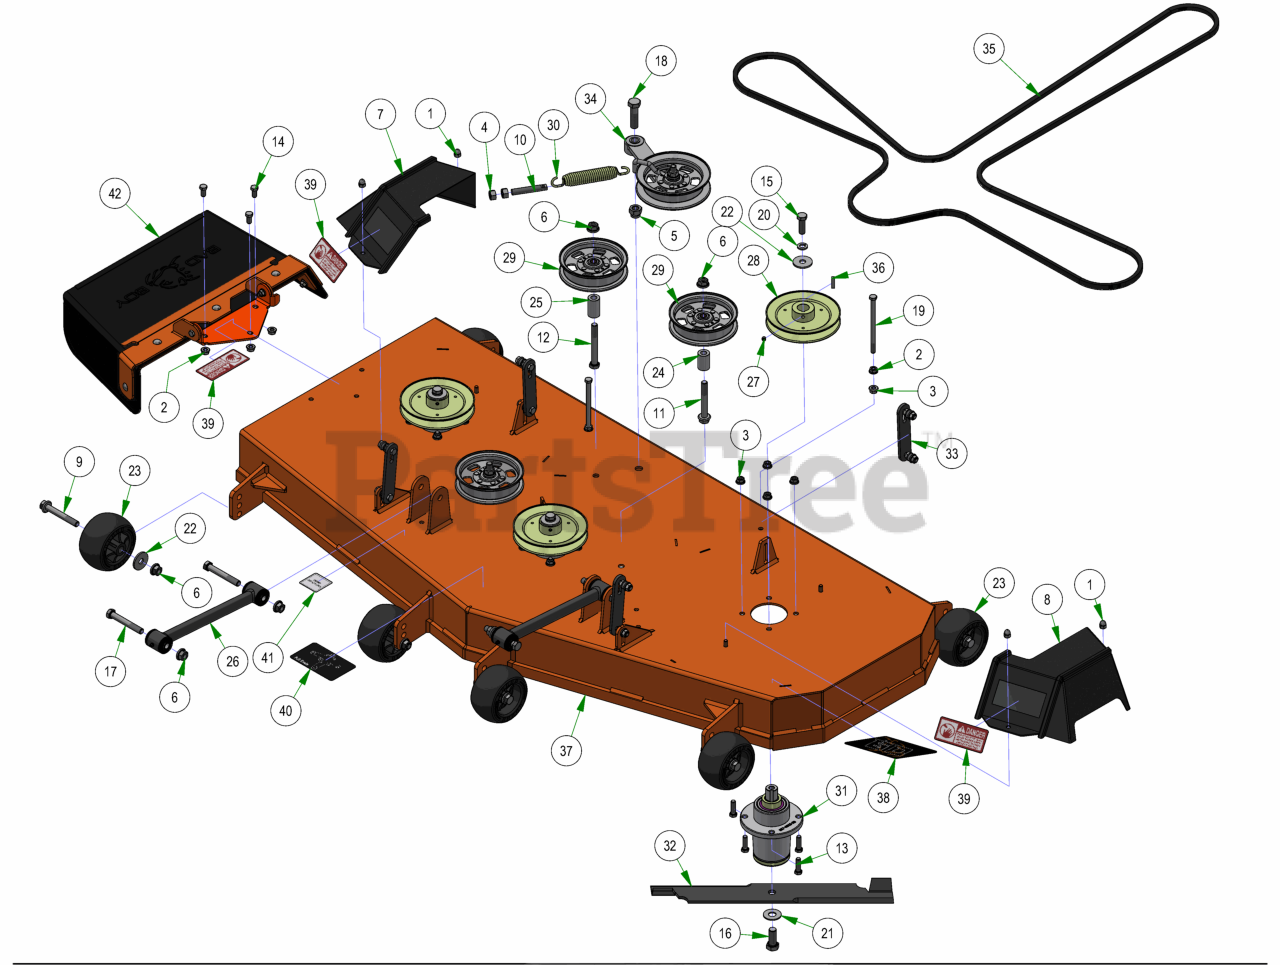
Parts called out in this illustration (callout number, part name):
1	5/16-18 ACORN NUT HIGH-CROWN ZC
2	3/8-16 HEX SERRATED FLANGE NUT HARD/ZINC
3	3/8-16 NYLON INSERT FLANGE LOCKNUT (GR.F) ZINC
4	1/2-13 HEX NUT ZINC
5	5/8-11 NYLON INSERT LOCKNUT ZINC
6	1/2-13 NYLON INSERT FLANGE LOCKNUT ZINC
7	2021 Maverick 54”/60” RH Pulley Cover
8	2021 Maverick 54”/60” LH Pulley Cover
9	1/2-13 X 90MM HEX FLANGE BOLT W/SHOULDER (GR.8) ZINC
10	All Thread
11	1/2-13 X 3-1/2 HEX FLANGE BOLT (GR.8) ZINC
12	1/2-13 X 4 HEX CAP SCREW (GR.8) ZINC YELLOW
13	3/8-16 X 1-1/4 HEX CAP SCREW (GR.5) ZINC
14	3/8-16 X 3/4 HEX CAP SCREW (GR.5) ZINC
15	1/2-20 X 1-1/2 HEX CAP SCREW (GR.5) ZINC
16	5/8-18 X 1-1/2 HEX CAP SCREW (GR.8) ZINC YELLOW
17	1/2-13 X 3-1/2 HEX CAP SCREW (GR.5) ZINC
18	5/8-11 X 2-1/4 HEX CAP SCREW (GR.5) ZINC
19	3/8-16 X 5-1/2 HEX CAP SCREW (GR.5) ZINC
20	1/2 SPLIT LOCKWASHER (GR.8) ZINC/YELLOW
21	5/8 USS FLAT WASHER (1-3/4" OD) GR.8 ZINC YELLOW
22	1/2 BELLEVILLE WASHER (1-5/8 OD X .140 THK) ZINC
23	Deck Wheel
24	.502 ID X .750 OD X 1.500 Long Spacer
25	1 3/4" Pulley Spacer
26	Hybrid Turnbuckle/Deck Locator
27	5/16-24 X 1/4 SOCKET SET SCREW (CUP PT) PLAIN
28	6 1/4" Drive Pulley
29	5-3/4 Idler Pulley
30	Deck Idler Spring
31	Spindle Assembly
32	60" High Lift Fusion Blade
33	Deck Hanger Assembly
34	Maverick HD & Down Deck Idler Assembly
36	1/4 X 1 SQ MACHINERY KEY 1018 STL PLN
37	2025 60" x 5" Deck
38	60" Grip Deck Decal
39	Danger Decal-Spindle/Discharge
40	Deck Belt Route Decal
41	Deck Impact Patent Decal 9591803
42	Discharge Chute Assembly
